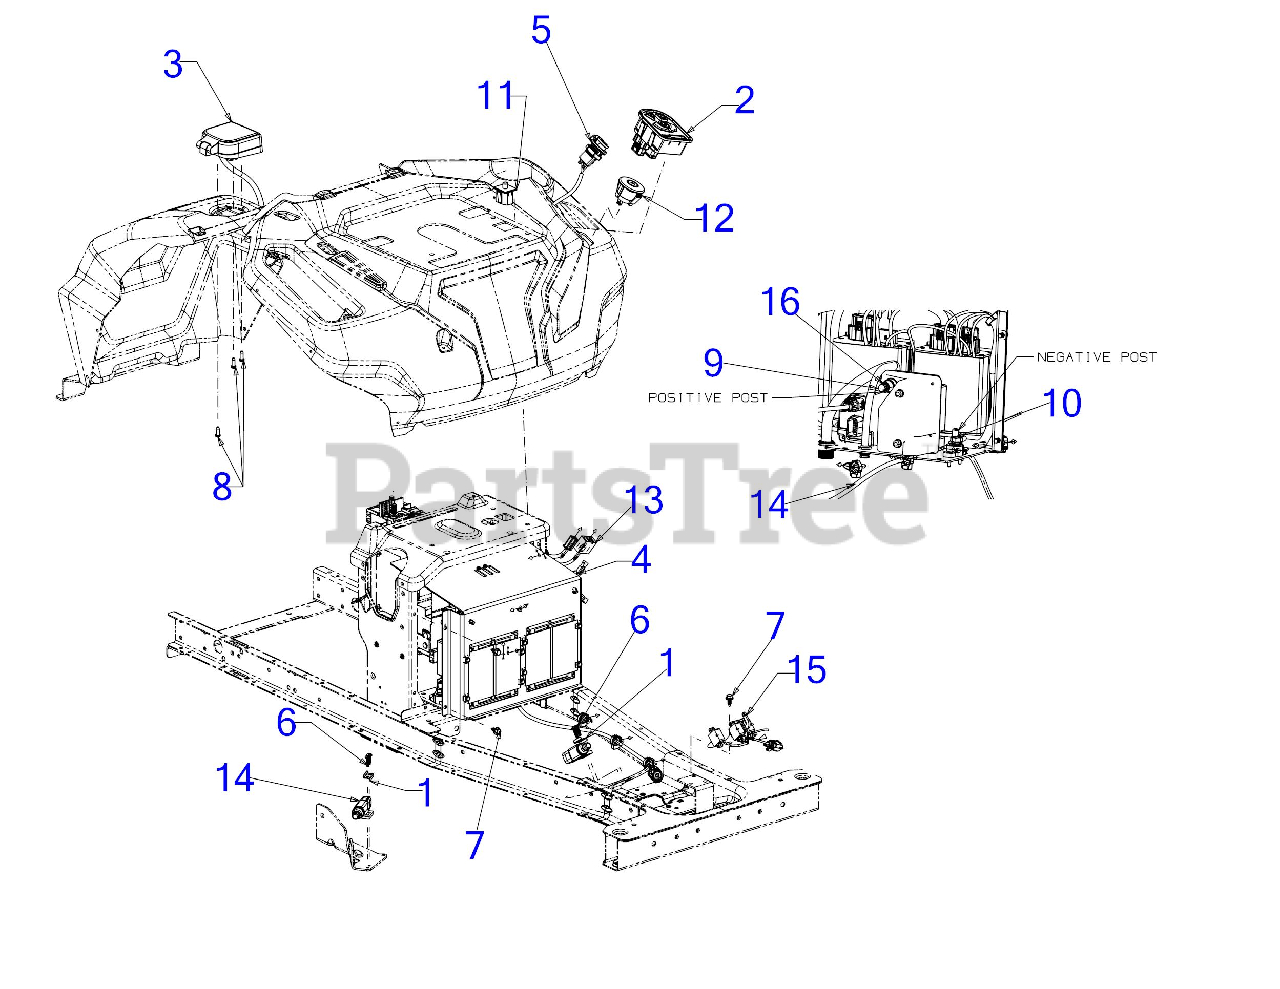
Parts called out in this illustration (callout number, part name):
1	PLATE-SWITCH
2	VCM MODULE
3	CHARGE PORT PLUG ASSEMBLY
4	MOTOR CONTROL PANEL
5	USB RECEPTACLE 12V W/JMPR
6	SCREW #10-24X11/16:T25
7	SCREW 1/4-20X.625
8	SCREW #12-16 x .625
9	SCREW 1/4-20X.5 GR5
11	SEAT SWITCH
12	KEY SWITCH 2 POSITION
13	MAIN WIRING HARNESS
14	PLUNGER SWITCH-NO/NO
15	THROTTLE SENSOR DUEL CLIP
16	LOCK WASHER
